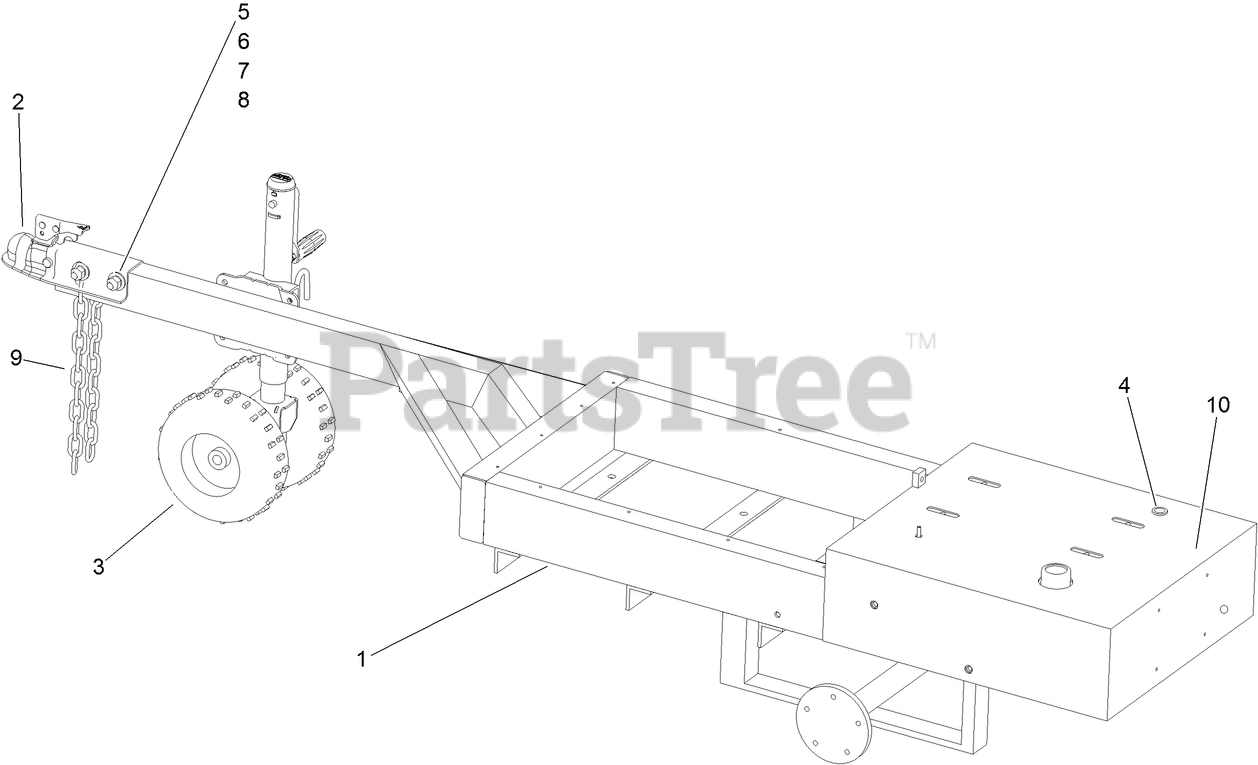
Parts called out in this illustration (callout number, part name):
1	CHIPPER TRAILER ASM
2	RECEIVER-HITCH, BALL
3	JACK ASM
4	GROMMET
5	BOLT-TAP
6	WASHER-FLAT
7	NUT-HH
8	WASHER-LOCK
9	CHAIN-SAFETY, TRAILER
10	MOTOR MOUNT ASM
